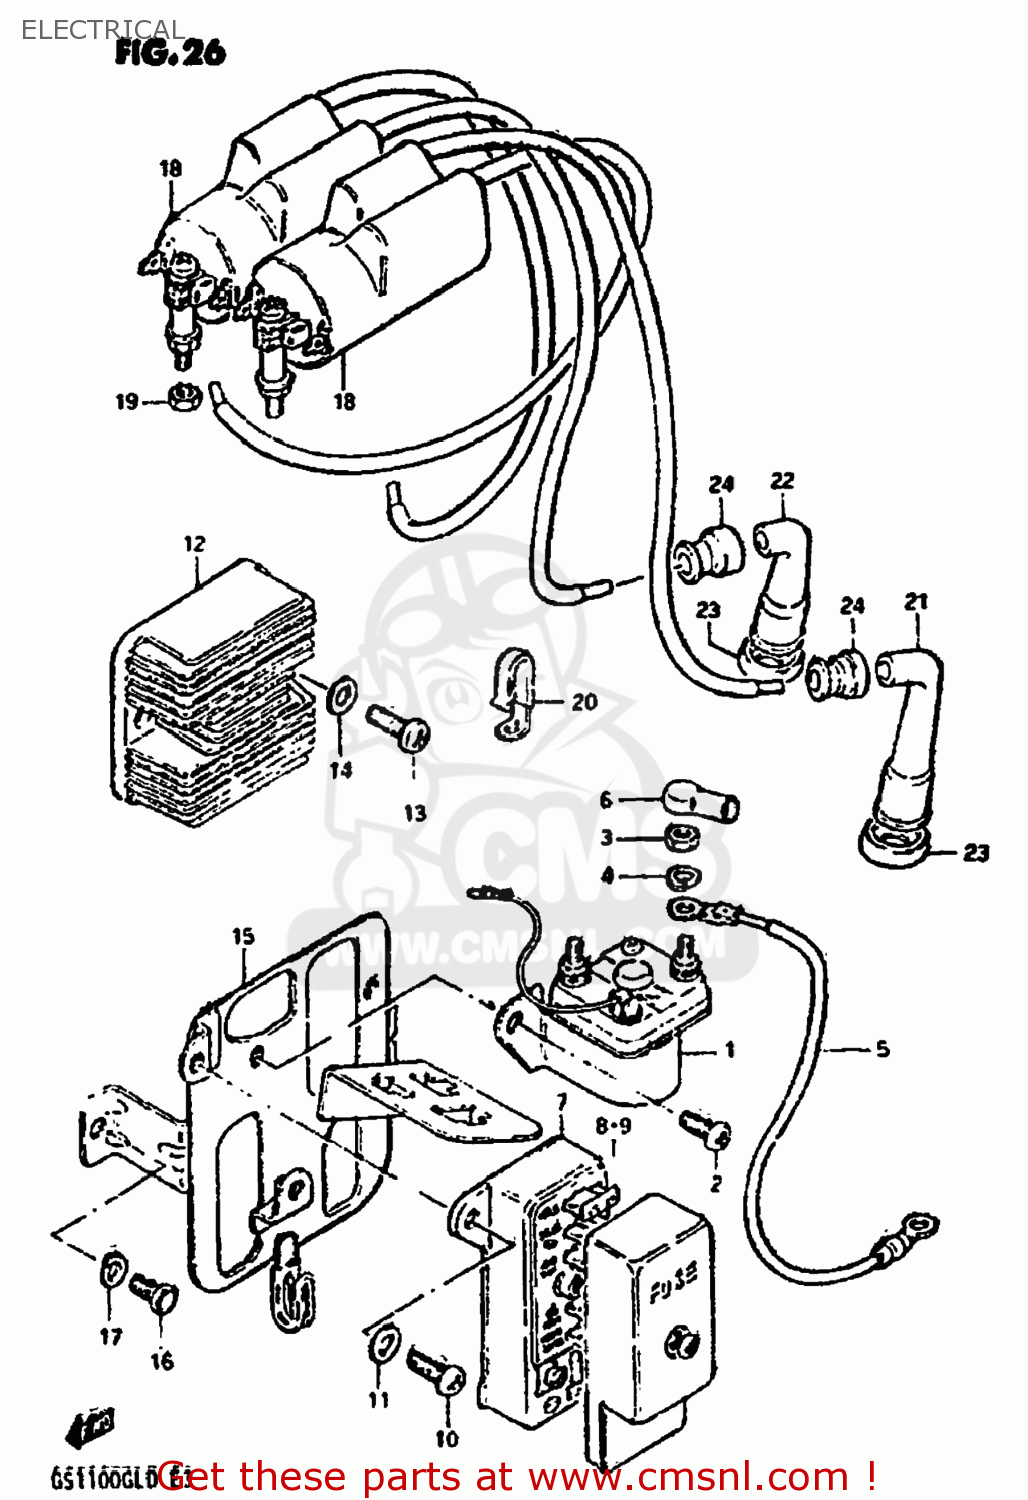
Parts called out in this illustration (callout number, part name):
1	RELAY ASSY,STARTING MOTOR
2	SCREW
3	NUT 6MM
4	LOCK WASHER
5	CABLE,STARTING MOTOR
6	CAP,STARTER RELAY
7	BOX ASSEMBLY,FUSE
8	FUSE(10A)
9	FUSE(15A)
10	SCREW 6X12
11	WASHER
12	RECTIFIER ASSEMBLY
13	SCREW 6X12
14	WASHER
15	HOLDER COMP,ELECTRONIC PARTS
16	BOLT
17	LOCK WASHER
18	COIL ASSEMBLY,IGNITION
19	NUT
20	CLAMP
21	CAP ASSY,SPARK PLUG
22	CAP,SPARK PLUG
23	SEAL,SPARK PLUG
24	SEAL,SPARK PLU
